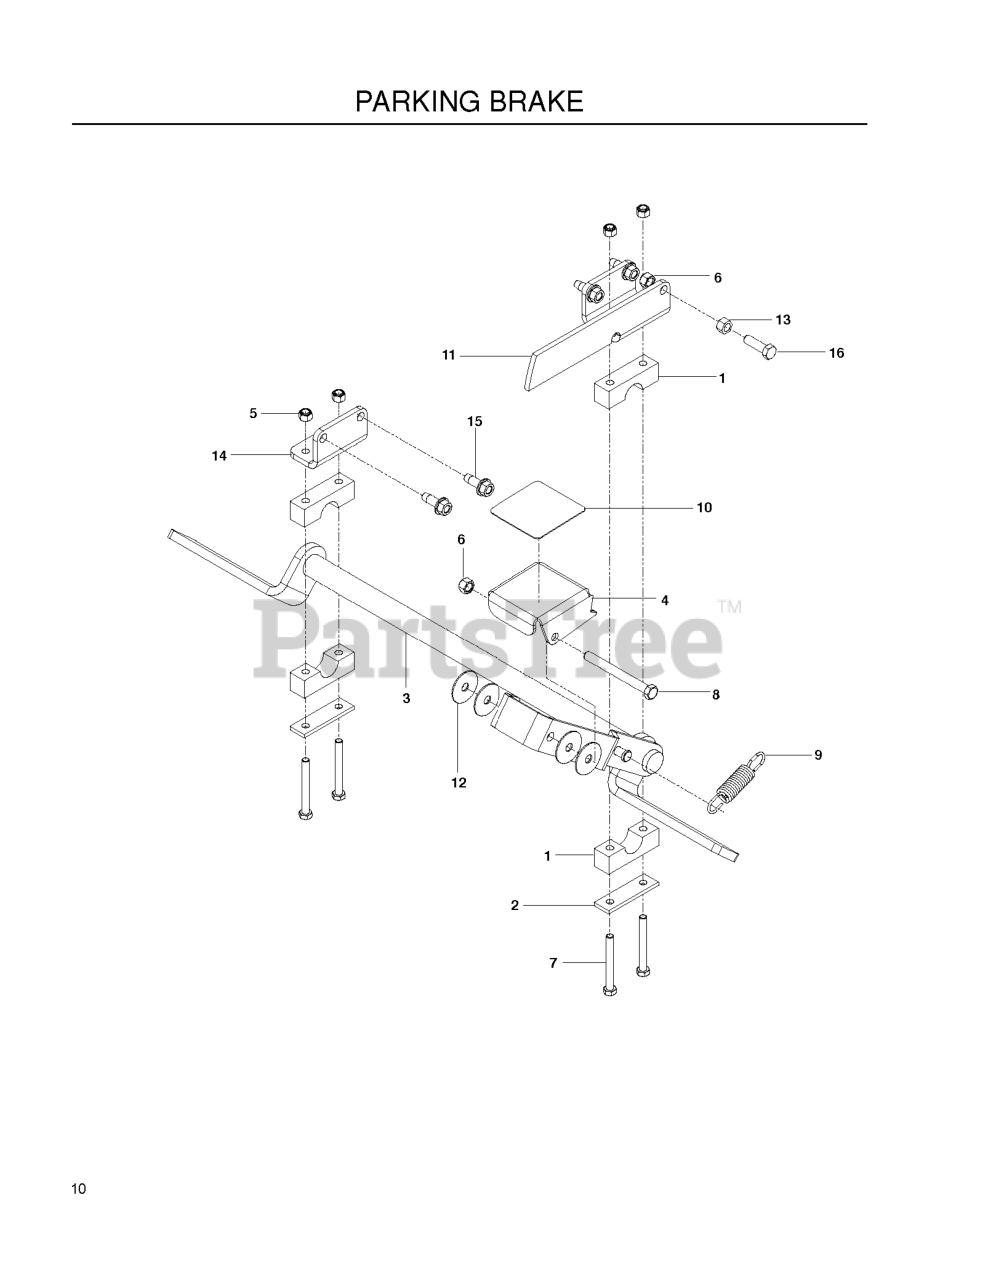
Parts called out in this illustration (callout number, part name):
1	PILLOW BLOCK
2	REINFORCEMENT BAR
3	PARK BRAKE
4	PEDAL, BLACK
5	NUT 5/16 NYLOC
6	NUT 3/8-16 NYLOC
7	HCS 5/16C X 2-3/4
8	HCS3/8-16.X
9	SPRING, EXTENSION
10	ANTI-SKID PAD
11	SUPPORT PLATE, P. BRAKE RH BLK
12	WASHER, FRICTION
13	NUT 3/8-16
14	SUPPORT PLATE, P. BRAKE LH BLK
15	BOLT 3/8-16 X 1.0
16	HCS 3/8C X 1 1/4 GR5
